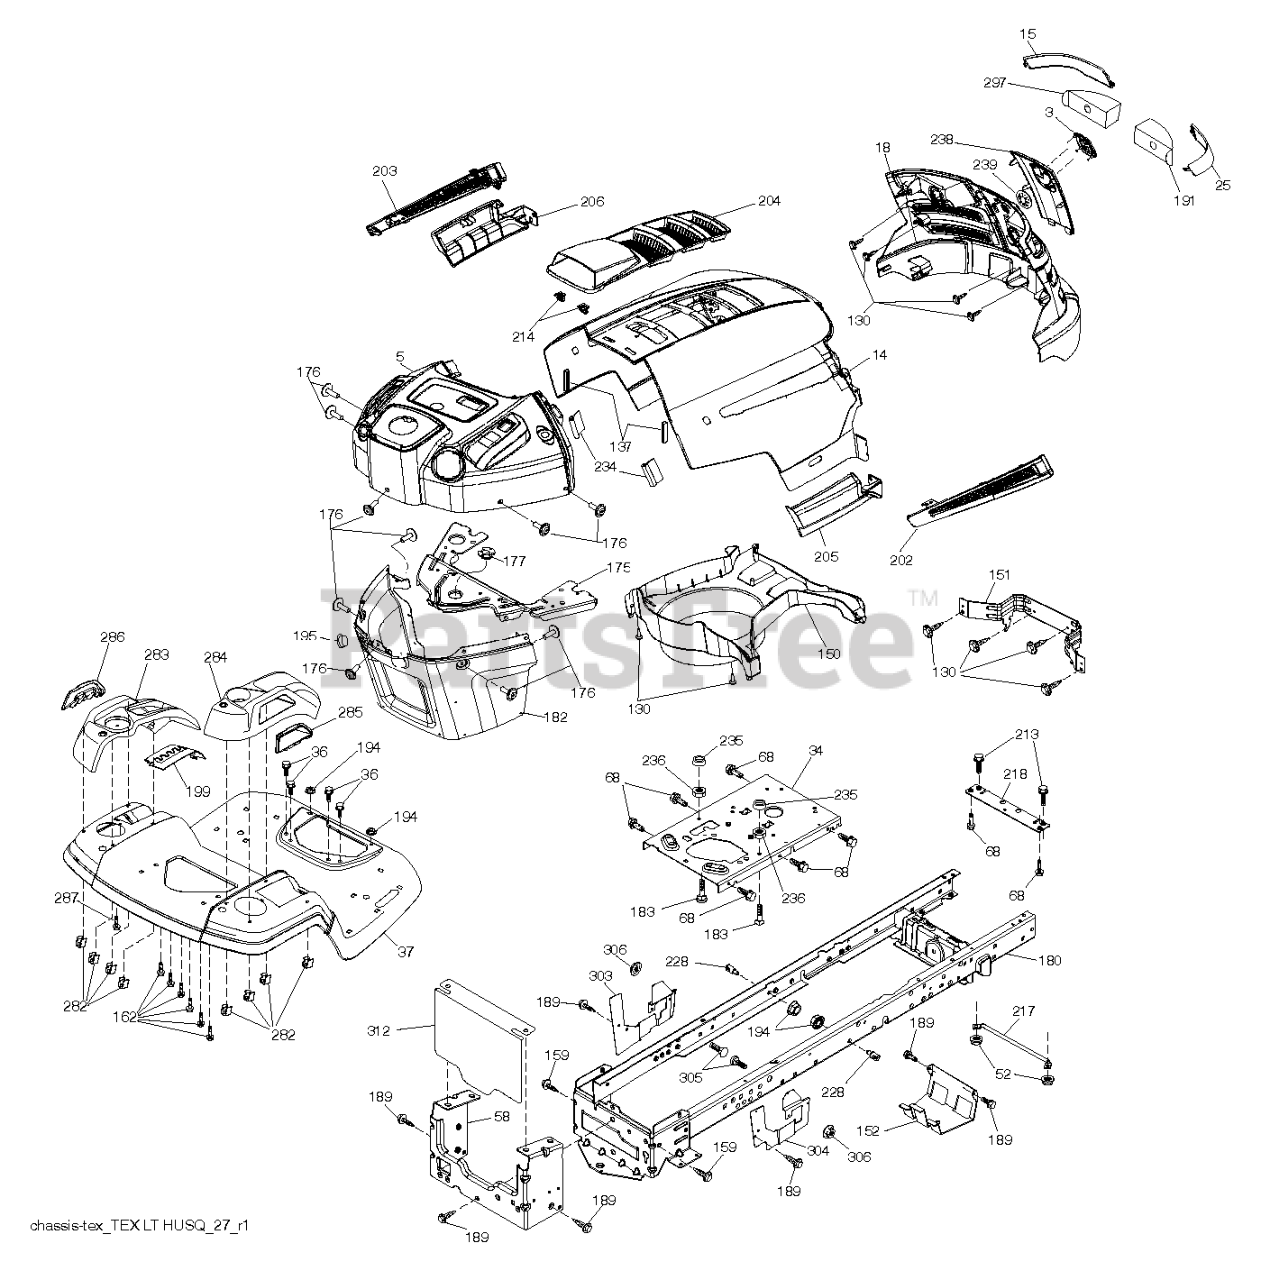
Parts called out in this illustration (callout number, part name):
3	RP LOGO
5	DASH
14	HOOD.HUSQVARNA.LT.ORANGE
15	LENS.HUSQVARNA LT.LH
18	GRILLE.SVC.HUSQVARNA.LT.GREY
25	LENS.HUSQVARNA LT.RH
34	PLATE.ENGINE.WELDED.CHASSIS
36	SCREW 5/16"
37	RP FENDER.TLT.FS.W/CPH.422
52	LOCKNUT
58	DRAWBAR UPPER 2PC SMALL FENDER
68	Screw 5/16-18 x 1/2 Hex, Self Tapping 5/16-18 x 1/2
130	SCREW.#10 X 0.750.BOS
137	BUMPER DASH
151	BRACKET PIVOT
152	SHIELD.BROWNING.W/TEX
159	SCREW, 3/8-16X3/4
162	SCREW.HI-LO.CONSOLE
175	CROSSMEMBER
176	SCREW.#10-24X5/8.RN.QU
177	BUSHING STEERING
180	CHASS.WLDMNT.TL.12GA/2P.48/54
182	DASH.LOWER.PREDATOR LT
183	BOLT.5/16-18X1-1/4 FULL THD
189	SCREW
191	INSERT.REFLECTIVE.RH.
194	NUT LOCK HEX FLANGE 5/16-18
195	PLUG DASH
199	PLATE.DECK.LIFT.HUSQ.LT
202	VENT SIDE HOOD LH
203	VENT SIDE HOOD RH
204	VENT TOP HOOD
205	SKIRT SIDE RH
206	SKIRT SIDE LH
213	BOLT
214	CLIP.RETAINER.TINNER.
217	ROD.PIVOT.HOOD
218	X-PIECE.HOOD.STOP.NON/
228	STUD.FASTNER.W/ANTI-ROTATE
234	BUMPER.HOOD.TEX.HUSQVARNA
235	SPACER FENDER
236	NUT.CENTERLOCK.5/16-
238	TRIM
282	CLIP.RETAINER.CONSOLE.LT.HUSQ
283	CONSOLE.DECK.LIFT.HUSQ.N/FR.GR
284	CONSOLE.SHFT.HYD,HUSQL
285	CONSOLE INSERT RH
286	CONSOLE.INSRT.LH.HUSQ.LT.BLACK
287	SCREW 1/4X20
297	INSERT REFLECTIVE
303	SHIELD CHASSIS LEFT
304	SHIELD CHASSIS RIGHT
305	BOLT
306	NUT LOCK FLG 3/8-16 UNC
312	SHIELD.PNT.DRAWBAR.FRENCH
